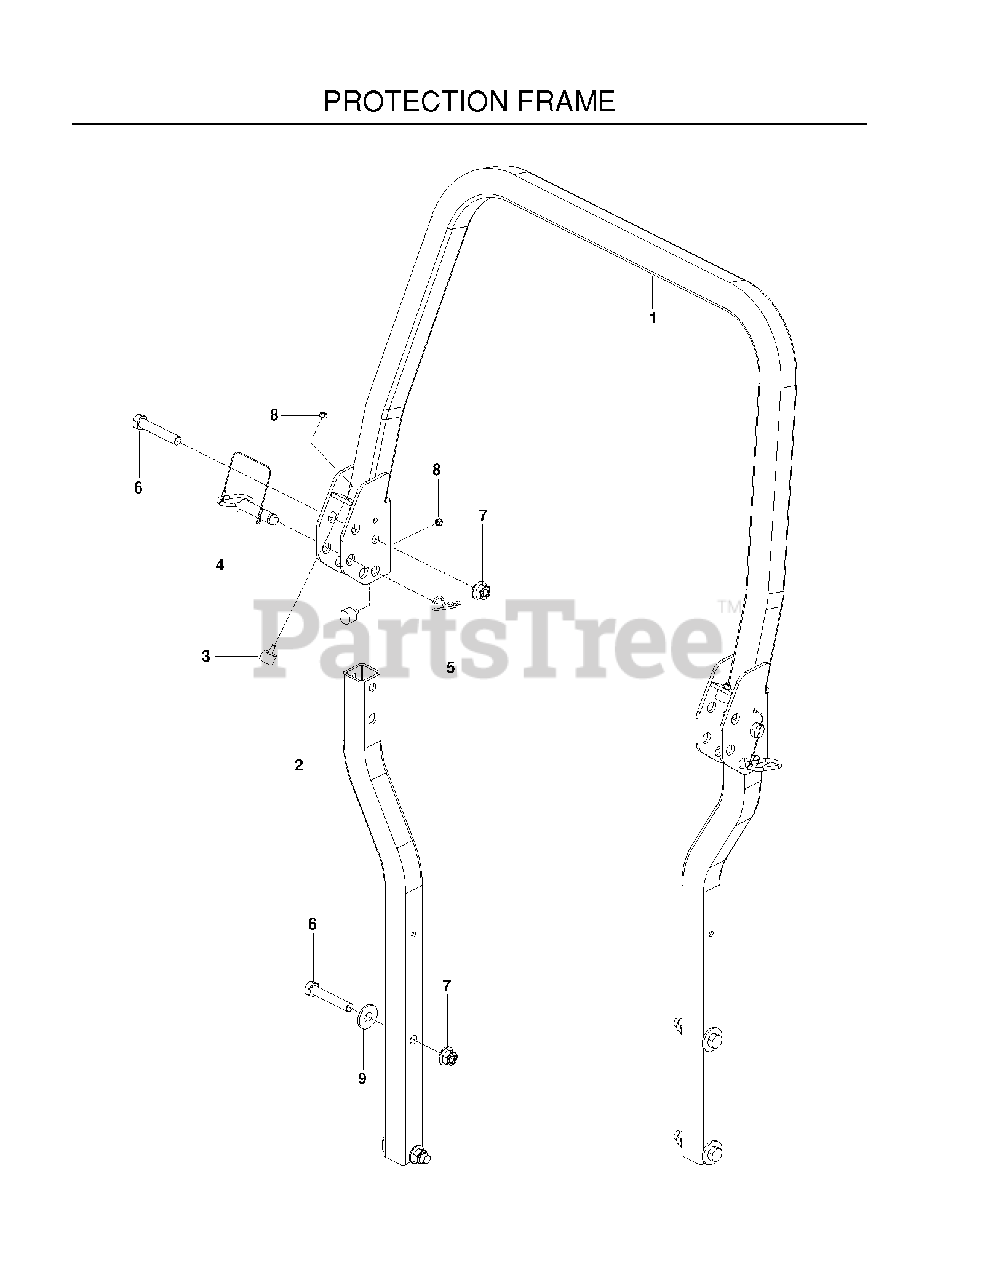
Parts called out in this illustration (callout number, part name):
1	ROPS.TOP.GRAY
2	TUBE.SIDE.ROPS.GREY
3	BUMPER, MALE STUD, 1/4-20
5	PIN HAIR .148 X 2-15/16 #210
6	5/8-11 X 3-1/2 HHB GRADE 5
7	NUT 5/8-11 FLG NYLOC ZD
8	RP_NUT 1/4-20 NYLOC
9	WASHER, 5/8 FLAT
